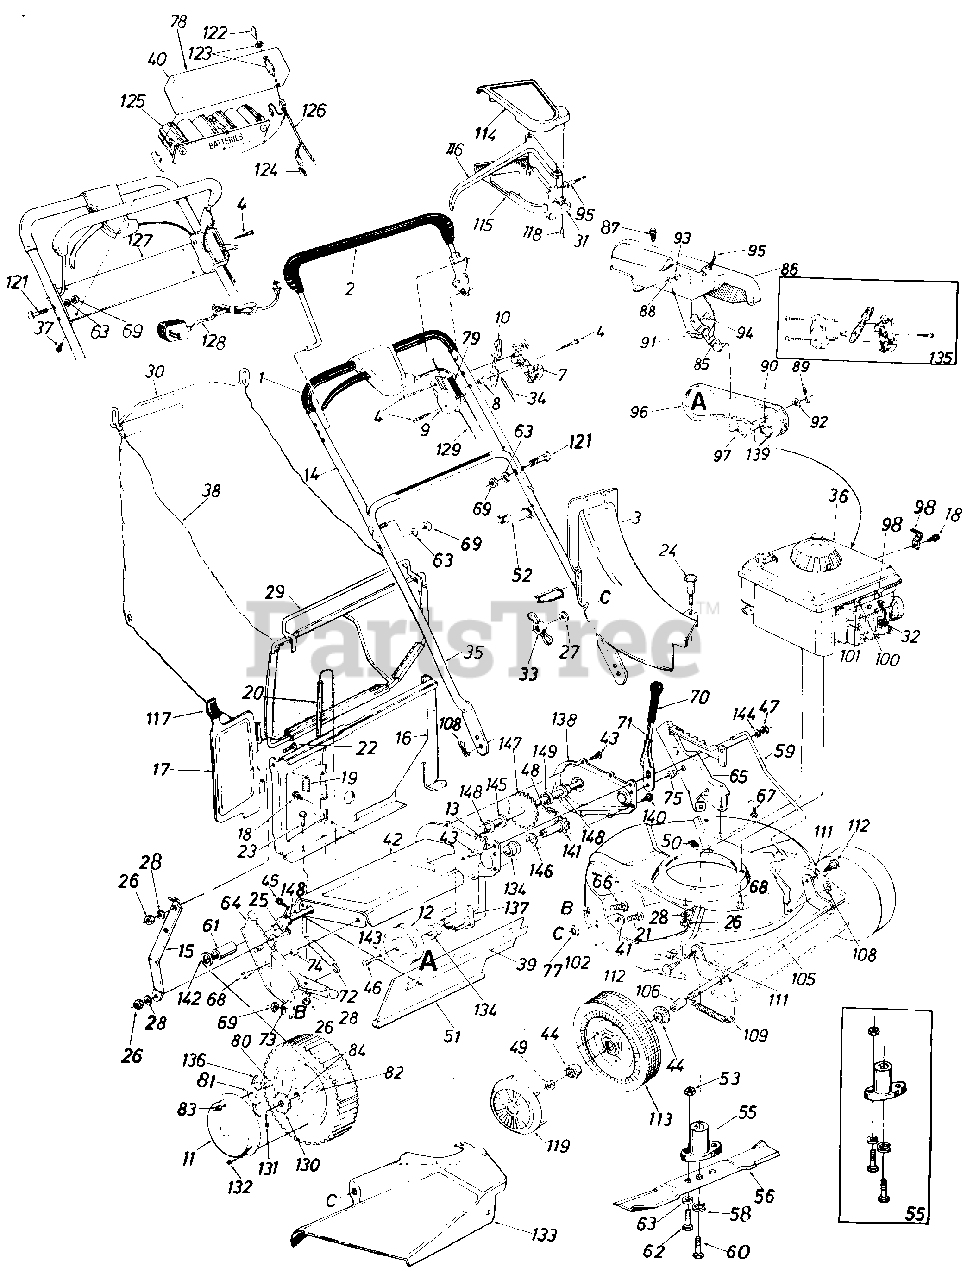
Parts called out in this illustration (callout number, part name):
2	Control Handle Ass'y.-L.H.
3	Top Discharge Chute Ass'y.
4	Truss Mach. Scr. #12 x 1.50" Lg.
7	Control Panel Half
8	Control Disc Pin
9	Clutch Panel Half
10	Throttle Control Lever
11	Hub Cap
12	1/2" V-Pulley
13	Cotter Pin 3/32" Dia. x .75
14	Upper Handle-Chrome
15	Panel Support Brkt.
16	Top Catcher Panel
17	Top Door
18	Hex B-Tap Scr. #10 x .38"
19	Torsion Spring
20	Pivot Pin
21	Carriage Bolt 1/4-20 x .62"
22	Truss Mach. Scr. 1/4-20 x .62" Lg.
23	Hex Bolt 1/4-20 x .50" Lg.
24	Shoulder Bolt .312 Dia. x .18 Lg. Special
25	Hex Bolt 1/4-20 x .62" Lg.*
26	Hex Nut 1/4-20 Thd.
27	Bell-Wash. 1/4" I.D.
28	L-Wash. 1/4" I.D.*
29	Front Grass Catcher Frame
30	Grass Catcher Handle
31	S.P. Control Cover
32	Spark Plug Insulator
33	Wing Nut
34	Throttle Control Wire 58"
35	Lower Handle-Chrome
36	Engine
37	Truss Mach. Hi-Riser Tap Scr. 1" Lg.
38	21" Top Discharge Grass Bag
39	Retaining Strip
40	Battery Tray
41	Fl-Wash. .344" I.D. x .62"
42	Chain-Axle Ass'y.
43	Hex 8-Tap Scr. 1/4" x .38" Lg.
44	Flange Ball Bearing 1/2" I.D.
45	Hex AB-Tap Scr. 1/4 x .62"
46	Hex Wash. TT-Tap Scr. 1/4-20
47	Hex Patch L-Nut 3/8-24 Thd.
48	#48 Chain .500" Pitch x .30 Links
49	Hex L-Nut 1/2-20 Thd.
51	Rear Flap 3.75" x 17.30" Lg.
52	Cable Tie
53	Hex Nut 5/16-24 Thd.
55	Blade Adapter Kit
56	21" Blade
58	L-Wash. 3/8" I.D.-H.D.
59	Height Adj. Rod 19.42" Lg.
60	Hex Bolt 3/8-24 x 2.25" Lg. (Grade 5)
61	Spacer .51 " I .D. x .69" O.D. x.69" Lg.
62	Hex Bolt 5/16-24 x 1.00" Lg. (Grade 5)
63	L-Wash. 5/16" I.D.*
64	R.H. Handle Wheel Brkt. Ass'y.
65	L.H. Handle Wheel Brkt. Ass'y.
66	Carriage Bolt 5/16-18 x .62"*
67	Hex Wash. Hd. B-Tap Scr. 5/1 6-1 8
68	Hex Wash. Hd. TT-Tap Scr. 3/8-1 6
69	Hex Nut 5/16-18 Thd.*
71	Height Adj. Lever
72	Extension Spring .50" O.D. x 3.80" Lg.
73	Bell-Wash. 5/16" I.D.
74	Spacer.385" I.D. x .502" O.D. x .270" Lg.
75	Shld. Spacer .500" Dia. x . 1 00
77	Bolt Retainer 1/4 x .50" O.D.
78	Instruction Label
79	Control Label
80	Shld. Scr. .342" Dia. x .268
81	Pawl
82	Wheel Ass'y. Comp.-Rear 8x 1.75
83	Hex Irls. L-Nut 1/4-20 Thd.
84	Flange Ball Bearing 1/2" I.D.
85	Belt Idler Bracket Ass'y.
86	Belt Cover
87	Hex Wash. S-Tap Scr. 1/4-20 x.50" Lg.
88	Hex Nut 1/4-20 Thd.*
89	Cotter Pin 1/8" Dia. x 1.00" Lg.*
90	Spring Pin Spir. 3/16" Dia. x 1.00" Lg.
91	Extension Spring .33" O.D. x 1.12" Lg.
92	Fl-Wash. .531" I.D. x .930" O.D. x .050
93	L-Wash. 1/4" I.D.*
94	Shld. Bolt .375" Dia. x .181
95	S.P. Cable x 53.0" Lg.
96	"V"-Belt 1/2" x 32.0" Lg.
97	Fl-Idler Plastic 1.62" Dia.
98	Casing Clamp
100	Hex B-Tap Scr. #10 x .62"
101	Casing Clamp
106	Sleeve .526" I.D. x .690" O.D. x .880" Lg.
108	Intern. Cotter Pin 5/16" Dia.
109	Extension Spring .50" O.D. x 3.20" Lg.
111	Intern. L-Wash. 3/8 I.D.*
112	Shld. Bolt .623" Dia. x .425
113	Front-Wheel Ass'y. Comp. 7x 1.50
114	Self-Propelled Control Cover
115	Self-Propelled Control Cover
116	Control Lever
117	Door Grip
118	Fl-"C"-Sunk Hd. Tap Scr. #10 x .75" Lg.
119	Hub Cap-Plastic
121	Curved Carr. Bolt 5/16-18 x 1.38" Lg.
122	Ignition Key
123	Ignition Switch
124	Plug
125	Battery Pack
126	Wire Harness
127	Lower Battery Tray
128	Battery Charger
129	Control Cable-43" Lg.
130	Ratchet Wheel 1.62" O.D.
131	Cotter Pin 1/8" Dia. x 1.00' Lg.*
132	Pan Hd. Tap Scr. #12 x .50" Lg.
133	Side Chute Deflector Ass'y
134	Flange Bushing
135	Kit-Control Housing Comp.
136	Spring-Nylon
137	Bearing Hub Flange Ass'y.
138	Chain Cover
139	Engine Pulley 1/2"
140	Hex Wash. S-Tap Scr. 1/4-20 x.50" Lg.
141	Sprocket-Shaft Ass'y.
142	Fl-Wash. .531" I.D. x .93" O.D.
143	Bell-Wash. .265" I.D. x .75" O.D.
144	Fl-Wash. .385" I.D. x .87" O.D.
145	Fl-Wash. .51" I.D. x 1.0" O.D.
146	Fl-Wash. .62" I.D. x 1.12" O.D.
147	Rear Shaft Ass'y. 22.05" Lg.
148	Hex Flange Bearing .506" I.D. Plastic
149	Spacer .510" I.D. x 1.00" O.D. x .210" Lg.
